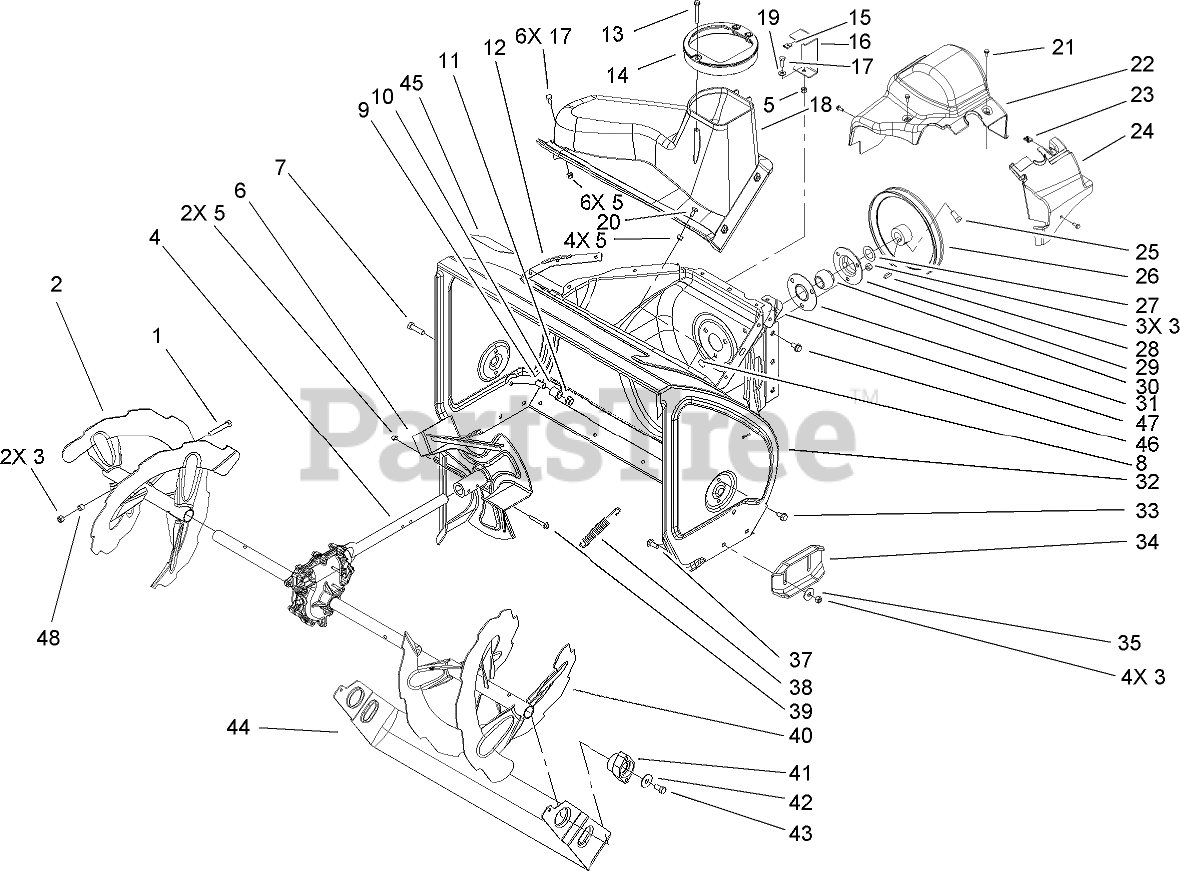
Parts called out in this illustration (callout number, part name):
1	SCREW-HH
2	RH AUGER ASM
3	NUT-LOCK, NI
4	28 INCH AUGER GEARCASE ASM
5	NUT-LOCK, NI
6	IMPELLER ASM
7	SCREW-HH
8	SCREW-CARR
9	SPACER-SCRAPER, STOP
10	CUSHION-SCRAPER, STOP
11	NUT-HF
12	SEAL-FLANGE, COVER
13	SCREW-PLASTITE
14	GUIDE-CHUTE
15	NUT-SPEED, U-TYPE
16	BRACKET-COVER, CLIP NUT
17	SCREW-HH
19	WASHER-FLAT
20	BOLT-CARR
21	SCREW-HWH
22	COVER-BELT
23	NUT-SPEED
24	COVER-EXTENSION, BELT
25	SCREW-SET, SQH
26	PULLEY-IMPELLER
27	WASHER-THRUST
28	KEY-WOODRUFF
29	FLANGE-CUP, BEARING
30	BEARING-BALL
31	FLANGE-CUP, BEARING
32	HOUSING-AUGER, 28 INCH
33	SCREW-HWHTF
35	WASHER
37	SCREW-CARR
38	SPRING-SCRAPER
39	SCREW-HHF
40	LH AUGER ASM
41	BEARING-AUGER
42	WASHER
43	SCREW-HH
44	SCRAPER-PIVOTING, 28 INCH
45	DECAL-DANGER, AUGER
46	SCREW-HWHTF
48	SPACER
